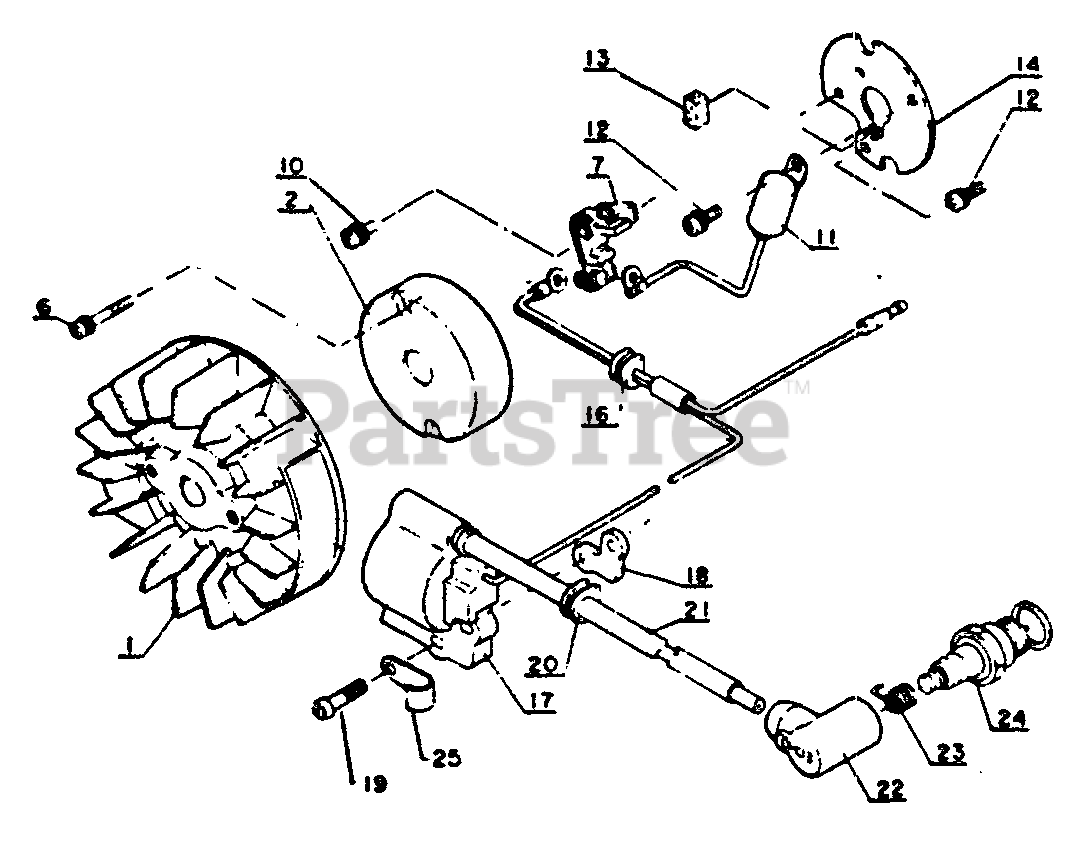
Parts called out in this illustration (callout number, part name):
1	FLYWHEEL
2	COVER, BREAKER
6	SCREW 3×22
7	CONTACT POINT SET
10	SCREW 4×8
11	CONDENSER
12	SCREW 4×12
13	OILER
14	STATER PLATE
17	COIL, IGNITION
19	SCREW 4×20
20	BUSHING
21	TUBE, INSULATOR
22	CAP, SPARK PLUG
23	TERMINAL, SPARK PLUG
24	SPARK PLUG - BM6A
25	CLIP, CORD
